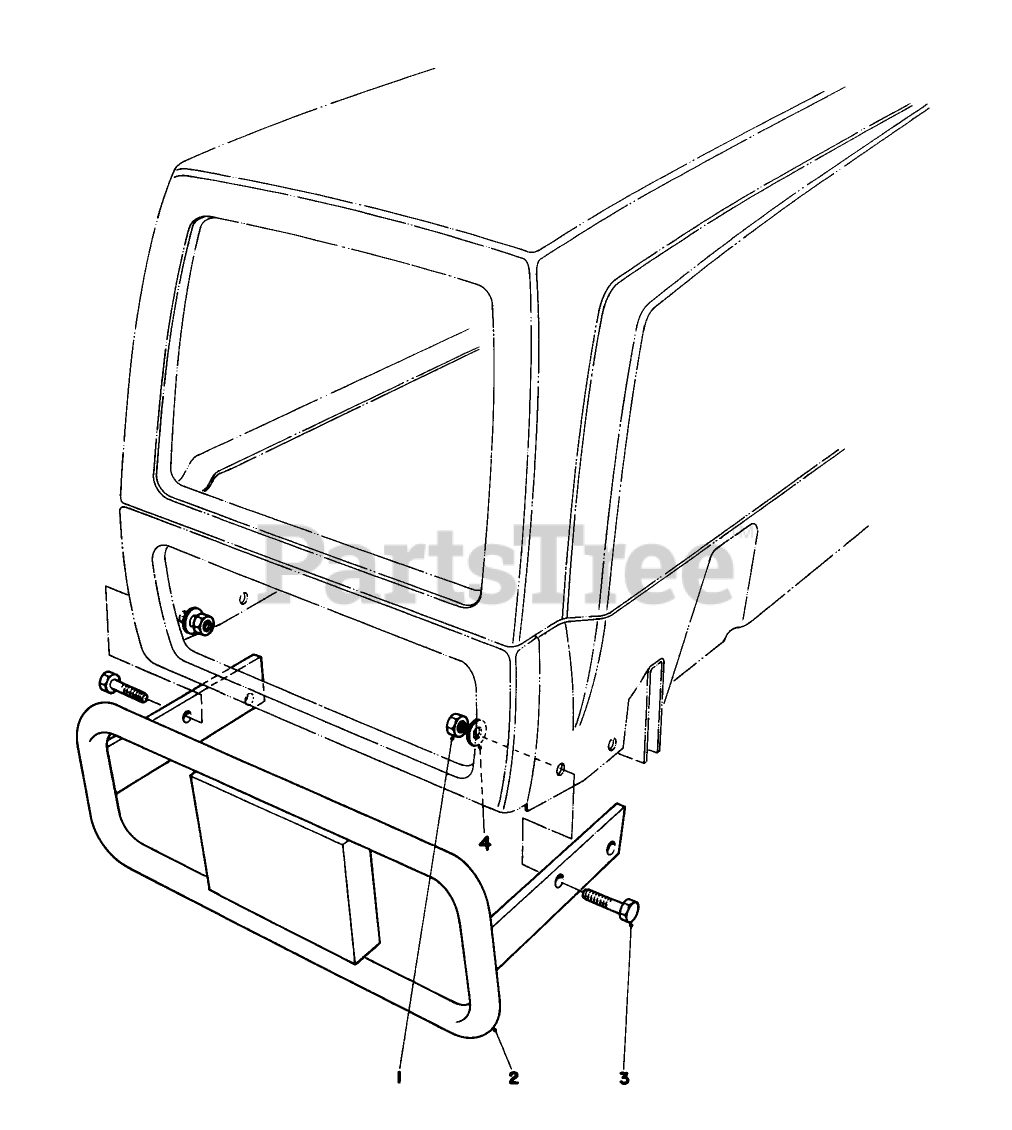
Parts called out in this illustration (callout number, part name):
1	NUT-LOCK, CONE
2	Bumper
3	SCREW-HH
4	WASHER-PLAIN
